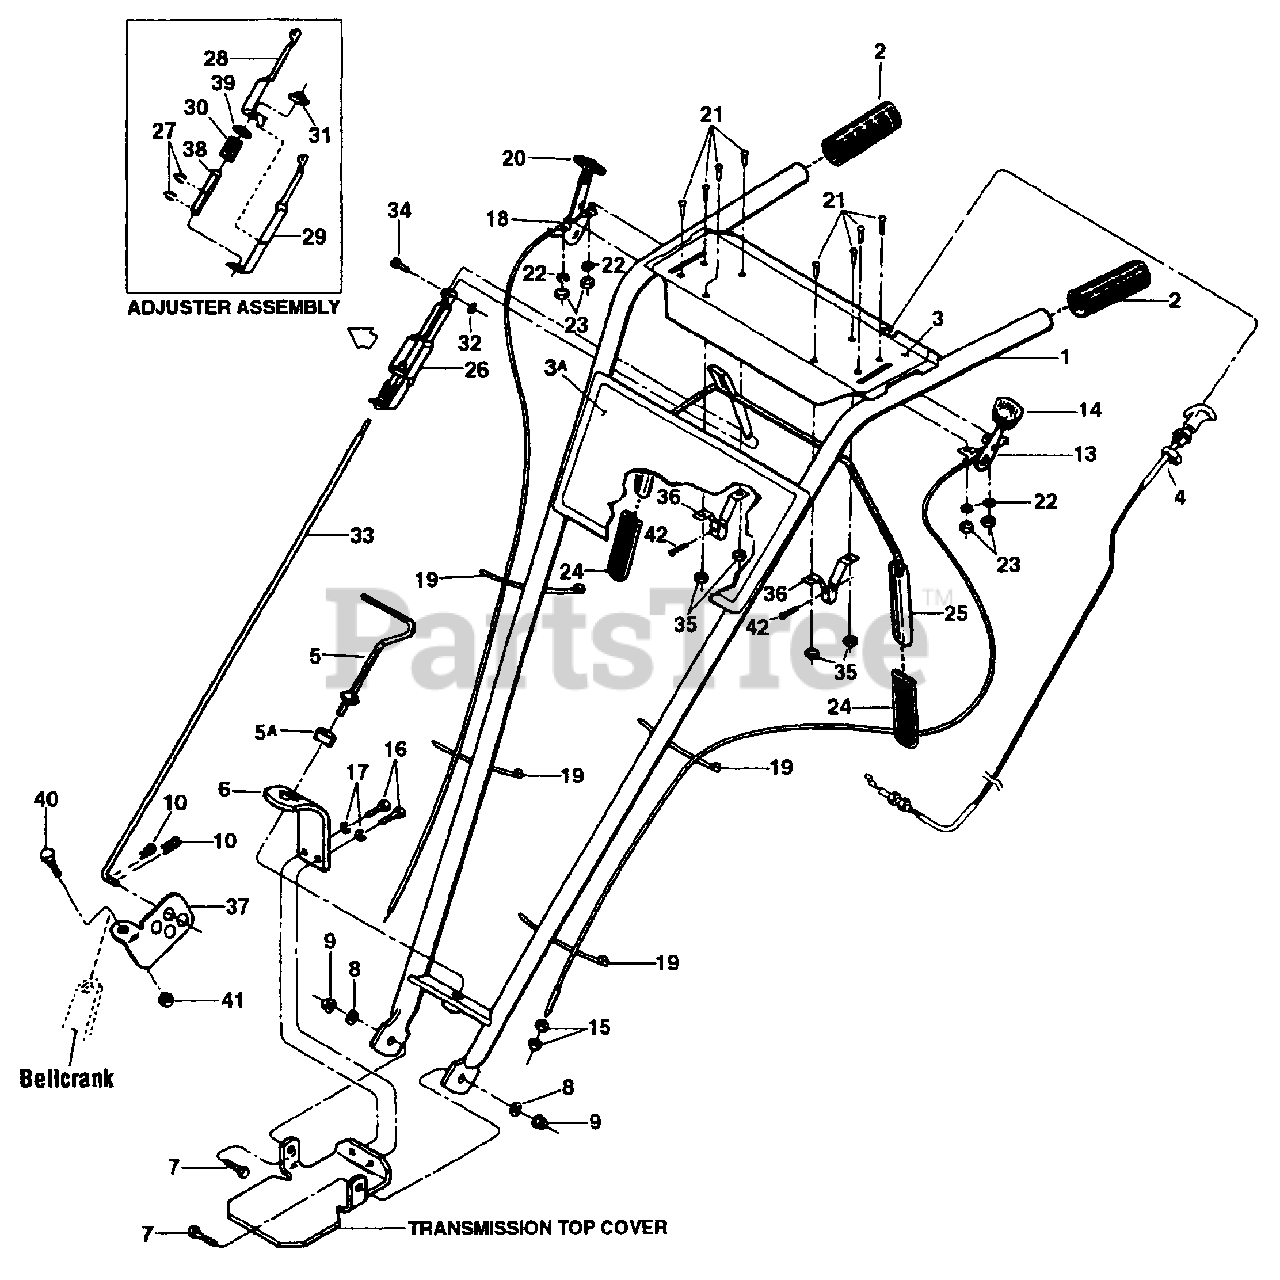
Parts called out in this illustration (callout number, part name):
1	Handlebars
2	Grip-handlebars
3	Decal-for operator control panel
3A	Decal-Troy-Bilt Pony (model name, logo)
4	Reverse Clutch Control Cable
5	Handle, Height Adjustment
5A	Washer-keyed
6	Bracket-handlebar height adjust
7	Screw-hex hd., 3/8-16 x 1
8	Washer-plain (flat) 3/8, S.A.E
9	Locknut-hex, 3/8-16
10	Hair Pin Cotter
13	Wheel Gear Control & Cable Assy.
14	Knob-wheel gear control lever
15	Nut-hex, 5/16-24, wheel gear cable adjustment
16	Screw-hex hd., 3/8-16 x 3/4
17	Lockwasher-3/8
18	Engine Throttle Control & Cable
19	Ties-plastic
20	Knob-throttle control lever
21	Screw-round hd, No. 10-32 x 1/2
22	Lockwasher-No. 10
23	Nut-hex, No. 10-32
24	Grip-paddle
25	Bail-forward clutch control
26	Adjuster Assembly
27	Klip Ring
28	Adjuster, Right Side
29	Adjuster, Left Side
30	Spring-Adjuster
31	Nut-rectangular
32	Klip Ring
33	Rod-forward clutch
34	Pin-Clevis
35	Sems Nut
36	Bracket-bail support
37	Swivel
38	Bushing
39	Washer
40	Screw-hex hd., 1/4-20 x 3/4
41	Nut-1/4-20
42	Screw-flanged hex hd, self-tapping, 1/4-20 x 1/2
